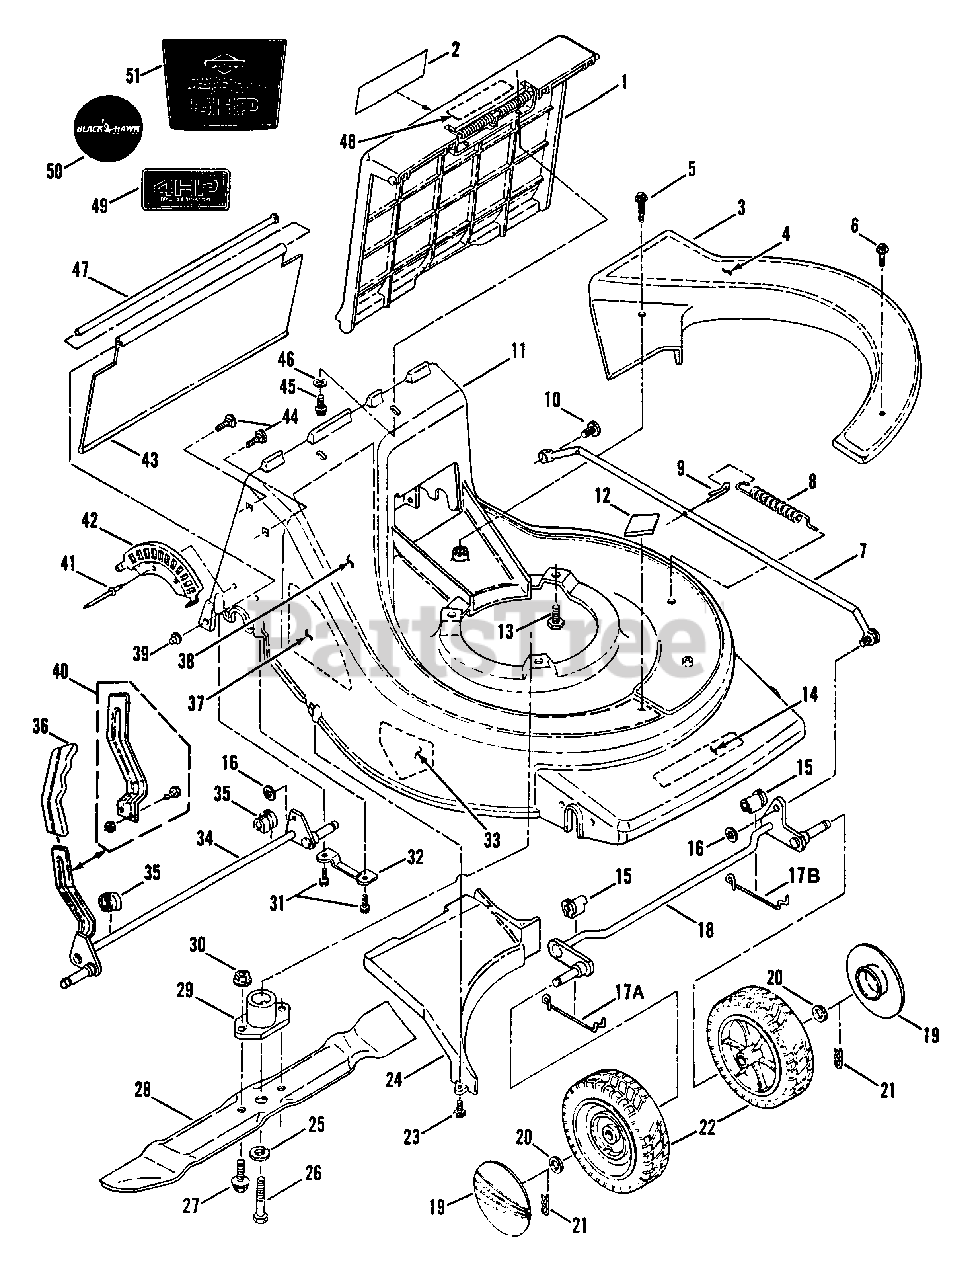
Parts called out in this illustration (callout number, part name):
1	ASSEMBLY, Discharge Door
2	DECAL, Discharge Door
3	COVER, Belt/Tie Bar
4	DECAL, Belt Cover
5	SCREW, #10-24 x 1-1/2" Slotted, Hex Washer Head, Self-Tapping
6	SCREW, #10-24 x 1" Slotted, Hex Washer Head, Self-Tapping
7	ASSEMBLY, Tie Bar
8	SPRING, Tie Bar
9	COTTER-PIN, 1/8 x 3/4"
10	PIN, Tie Bar, 3/8 x 5/8"
11	DECK, 21" Cast Aluminum
12	DECAL, Premium Quality Medallion
13	SCREW, 3/8-16 x 1" Hex Head, Self-Tapping
14	NAMEPLATE, BLACKHAWK
15	BUSHING, Front Axle
16	RETAINER, Wheel
17A	SPRING, Axle Retaining (Right Hand)
17B	SPRING, Axle Retaining (Left Hand)
18	ASSEMBLY, Front Axle
19	HUB-CAP
20	WASHER, 1/2" Flat
21	HAIRPIN, .062 x .900"
22	ASSEMBLY, Wheels
23	SCREW, #10-24 x 5/8" Slotted, Hex Washer Head, Self-Tapping
24	BAFFLE, Discharge
25	WASHER, 3/8 Split Lock (Heavy)
26	SCREW, 3/8-24 x 1-3/4" Hex Head Cap, Grade 5
27	BOLT, 3/8-16 x 1-1/4" Hx. Flg. Lk.
28	BLADE, 21" Bagging
29	HUB, Blade Drive
30	NUT, 3/8-16 Hex Nyloc
31	SCREW, 1/4-20 x 5/8" Hex Washer Head, Self-Tapping
32	SUPPORT, Rear Axle
33	DECAL - WARNING
34	ASSEMBLY, Rear Axle
35	BUSHING, Rear Axle
36	GRIP, Flat Bar
37	DECAL, Height Adjustment
38	DECAL, Cast Aluminum Deck
39	PUSH-NUT, 1/4"
40	KIT, Height Adjusting Lever
41	RIVET, 3/16 x 1/2" Steel
42	PLATE, Height Adjustment
43	SHIELD, Trailing
44	SCREW, 5/16-18 x 1" Carriage, Grade 5
45	SCREW, 1/4-20 x 5/8" Truss Head, Torx
46	WASHER, 1/4" Flat
47	ROD, Trailing Shield Pivot
48	DECAL - WARNING
49	DECAL, B. & S. 4HP Engine
50	DECAL, BLACKHAWK, Recoil Cover, B. & S. Engine
51	DECAL, B. & S. 5HP Engine
